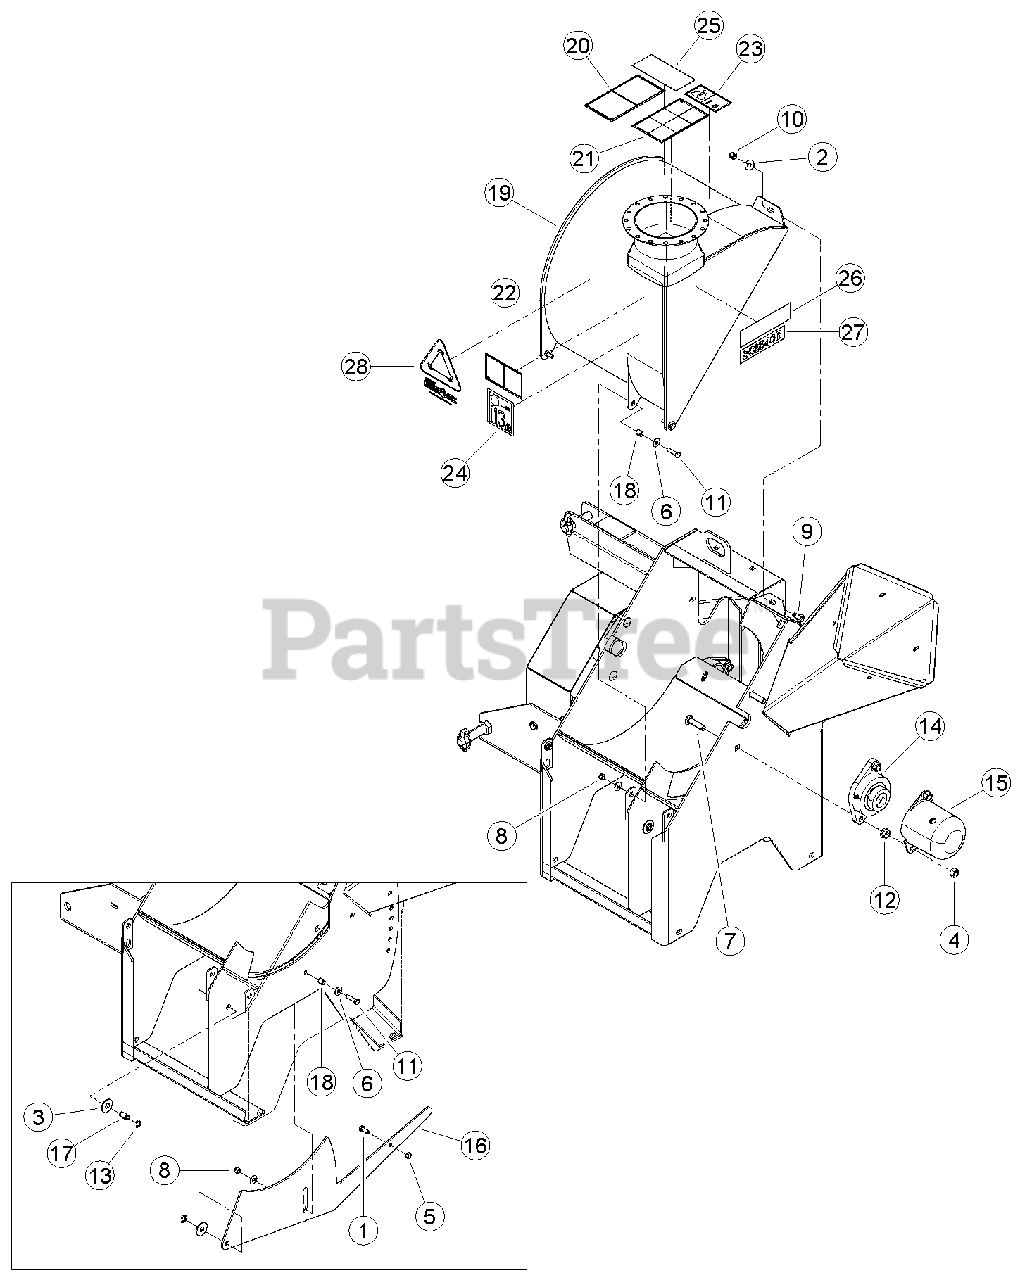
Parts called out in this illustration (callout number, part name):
1	BOLT, 5/16 X 3/4 HEX HD GR5 ZP
2	WASHER, 3/8 FLAT ZP
3	WASHER, 1/2 FLAT ZP
4	NUT, 1/2 CENTERLOCK GRB ZP
5	NUT, 5/16 CENTERLOCK NC ZP
6	WASHER, 5/16 FLAT ZP
7	BOLT, 1/2 X 2 CRG GR5 ZP
8	NUT, 5/16 NE NYLOCK ZP
9	BOLT, 3/8 X 1-1/4 CRG GR5 NC ZP
10	NUT, 3/8 NE NYLOCK ZP
11	BOLT, 5/16 X 1-1/4 HEX HD GR5 NC ZP
12	NUT, 1/2 SERR FLANGE NC ZP
13	CLIP, 1/2" E
14	BEARING,2 BLT FLG 1-1/2" BORE
15	CAP, LARGE SHAFT
16	ADJUSTOR, SHREDDER
17	PIN, RETAINER
18	SPACER, .50 X .50
19	ASSEMBLY, CHIPPER TOP SERVICE PART
20	DECAL, KNIFE ACCESS ISO
21	DECAL, OPERATING INSTRUCTIONS ISO
22	DECAL, DISCHARGE ISO
23	DECAL, MAINTENANCE ISO
24	DECAL, 113 DB
25	DECAL, MUTILINGUAL MANUAL
26	DECAL, ECHO BEARCAT 6.82 X 1.90
27	DECAL, MODEL SC5540B
28	DECAL, SHRED IT
